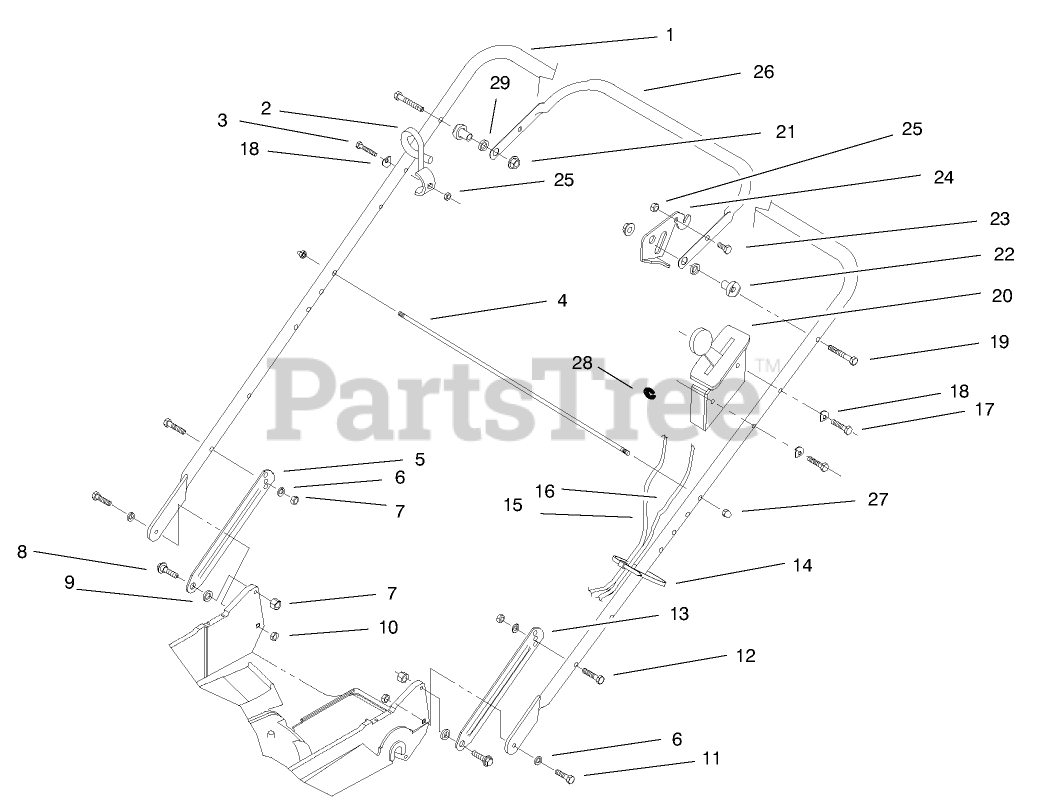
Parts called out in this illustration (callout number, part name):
2	GUIDE-ROPE
3	SCREW-HH
4	ROD-SUPPORT, BAG
5	LATCH-HANDLE, RH
6	WASHER-BELLEVILLE
7	NUT-LOCK, NI
8	SCREW-SHOULDER
9	SPACER
10	NUT-LOCK, NI
11	SCREW-HH
12	SCREW-HH
13	LATCH-HANDLE, LH
14	TIE-CABLE
15	CABLE - BRAKE
16	CABLE - THROTTLE
17	SCREW-HH
18	WASHER
19	SCREW-HH
20	BRACKET-THROTTLE CONTROL HEAD
21	NUT-LOCK, NI
22	SPACER-SUPPORT
23	SCREW-HH
24	LEVER-CONTROL
25	NUT-LOCK, NI
26	BAR-CONTROL
27	NUT-CAP
28	E-RING
29	SPACER-NYLON
